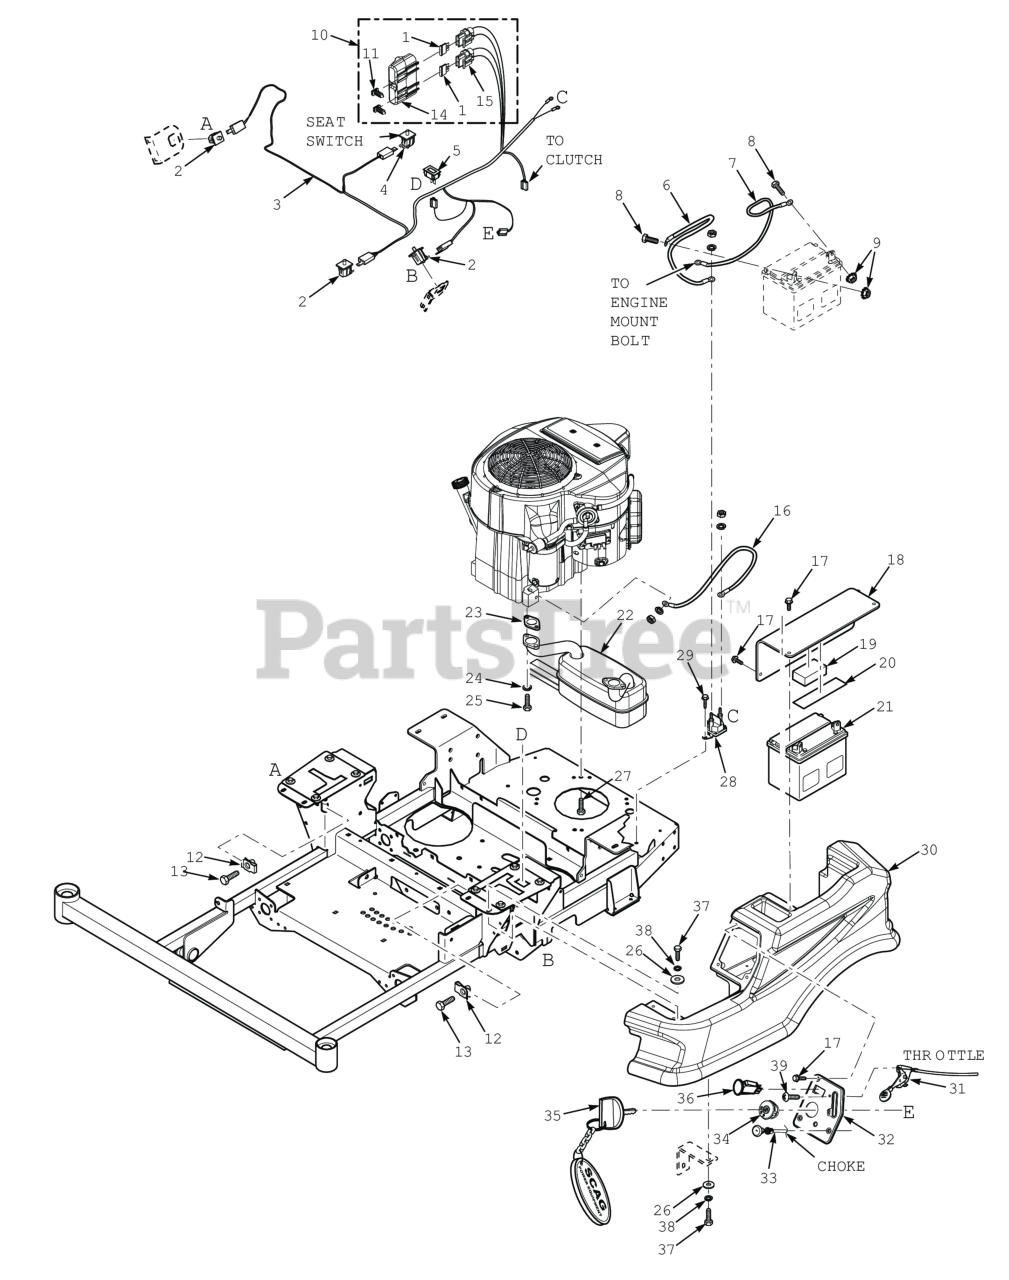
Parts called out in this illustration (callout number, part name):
1	FUSE, 20 AMP BLADE TYPE AUTOMOTIVE
2	Switch, Double Pole - Plunger
3	Wire Harness, Main
4	Switch, Double Pole - Plunger
5	Hour Meter, Inductive
6	Battery Cable, 25" Red (Kawasaki)
7	Battery Cable, 27" Black (35BV & 37BV-EFI) - Briggs & Stratton
9	Bolt, Hex Head 1/4-20 x .5" Battery, (Not Available Through Scag)
9	Nut, 1/4 - 20 Hex
10	Double Fuse Assy.
11	Clip, Fuse Holder
12	U-Nut, 3/8-16 (short)
13	Bolt, Hex Head 3/8-16 x 1-1/4" with Thread Lock Patch
14	Cover, Sealed Double
15	Fuse Holder Assembly
16	Battery Cable, Red 9" (Briggs & Stratton)
17	CAP SCREW, 1/4-20 X 1/2" SERRATED FLANGE HEX
18	Battery Cover (incl. items 19 & 20)
19	Pad, Battery - Rubber
20	Rubber Pad
21	Battery, 350 CCA (not available through Scag)
22	Muffler, Kohler KT
23	Exhaust Gasket
24	Flatwasher, 5/16-.375 x .875 x .083 (35BV & 37BV-EFI)
25	Bolt, Hex Head 3/8-16 x 1-1/4", Kawasaki FX / FT & FT-EFI
26	Lockwasher, 3/8" Spring, Kawasaki FX / FT & FT-EFI / B&S 32BV
27	Bolt, Hex Head Self-Tap 3/8-16 x 1-1/4" (Kohler x3 - 25EFI, Kohler x4 - 29EFI)
28	Solenoid, Sealed (Briggs & Stratton)
29	Screw, 1/4-20 x .375"
30	Tank Console 48
31	Throttle Control, Kawasaki
32	INSTR PANEL W/ DECAL, SFZ
33	Choke Control, Kawasaki
34	Ignition Switch
35	Key, Assembly w/Fob
36	Switch, PTO - 10 Amp
37	BOLT, SERRATED FLANGE HEX HEAD 5/16-18 X 3/4"
38	Lockwasher, 5/16 (.317 x .586 x .078) Helical Spring
39	Bolt, Carriage #10-24 x 1/2"
